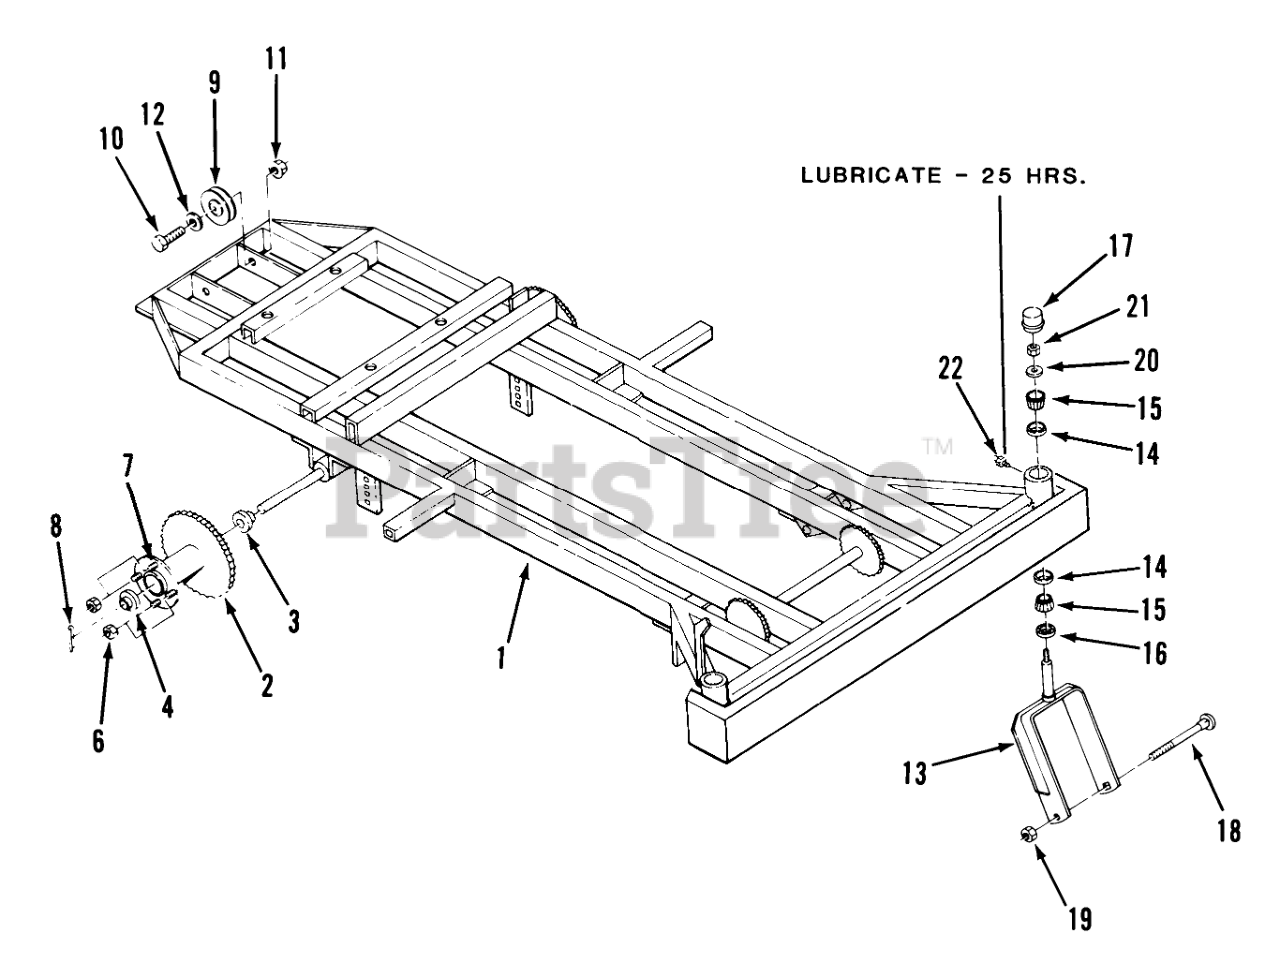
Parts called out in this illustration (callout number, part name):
1	Frame w/Bumper
2	Rear Wheel Hub
3	Rear Hub Axle Bearing-Inner
4	BEARING REAR LH
6	Wheel Lug Nut 1/2-20
7	BOLT STUD 1/2-20X1 1
8	Roll Pin
9	PULLEY-IDLER
10	Bolt
11	NUT
12	Washer
13	Front Wheel Forks
14	Front Fork Race
15	Front Fork Cones
16	Front Fork Seals
17	Dust Cap
18	Hex Bolt 5/8-11 x 7
19	E.S. Nut 5/8-11
20	Cupped Washer
21	Slot Nut 3/8-24
22	Zerk
